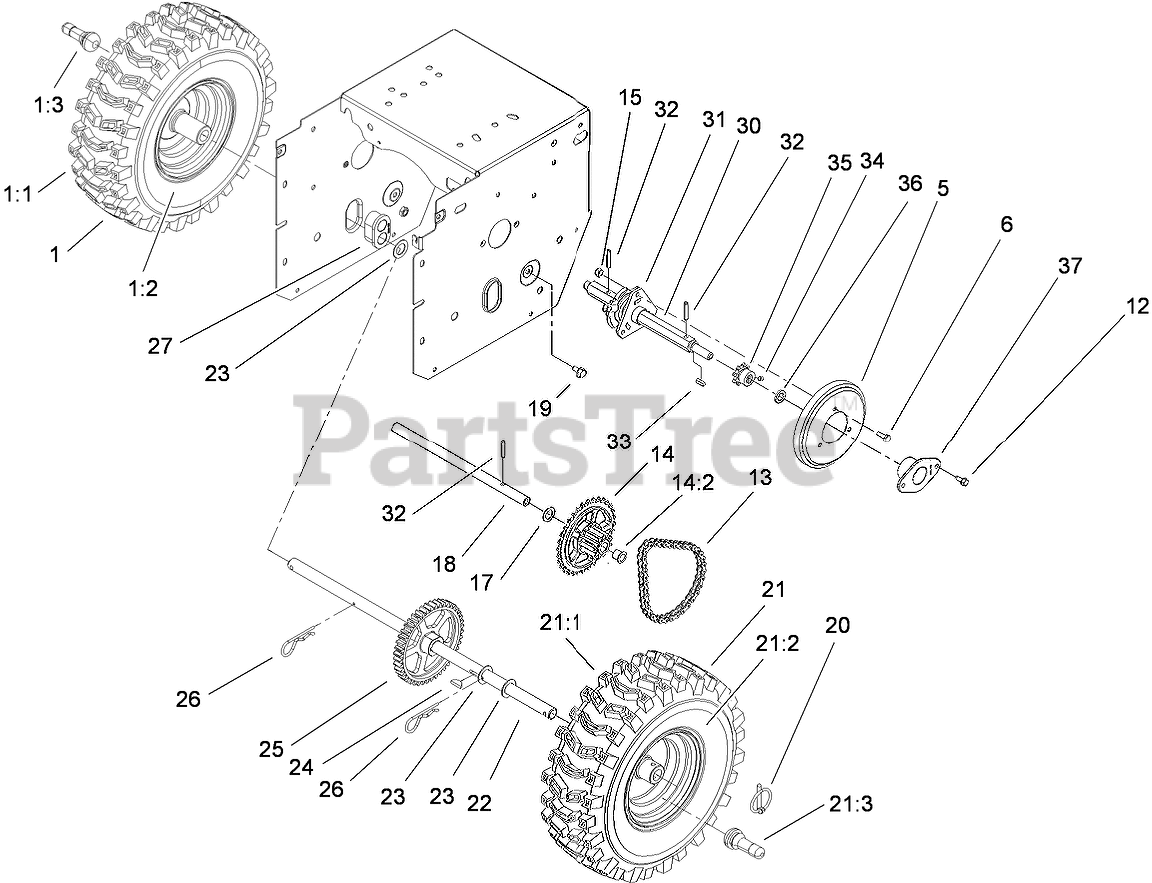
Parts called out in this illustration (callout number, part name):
1	RH WHEEL AND TIRE ASM
1:2	RIM-TIRE
1:3	STEM-VALVE
5	WHEEL-FRICTION
6	SCREW-HH
12	SCREW-HWH
13	CHAIN-ROLLER
13	LINK-CONNECTING
14	SPROCKET ASM
14:2	BUSHING-FLANGE
15	NUT-LOCK, NI
17	WASHER-FLAT
18	SHAFT-INTERMEDIATE
19	SCREW-HWHTF
20	KLIK PIN ASM
21	LH WHEEL AND TIRE ASM
21:2	RIM-TIRE
21:3	STEM-VALVE
22	SHAFT-AXLE
23	WASHER-THRUST
24	KEY-WOODRUFF
25	GEAR-AXLE, 44 TOOTH
26	PIN-HAIR
27	BEARING-AXLE
30	SHAFT-HEX
31	TRUNNION-HEX
32	PIN-ROLL, SLOTTED
33	KEY-SQUARE
34	SCREW-HSH
35	SPROCKET-8 TOOTH
36	SPACER-BUSHING
37	RETAINER-BEARING
